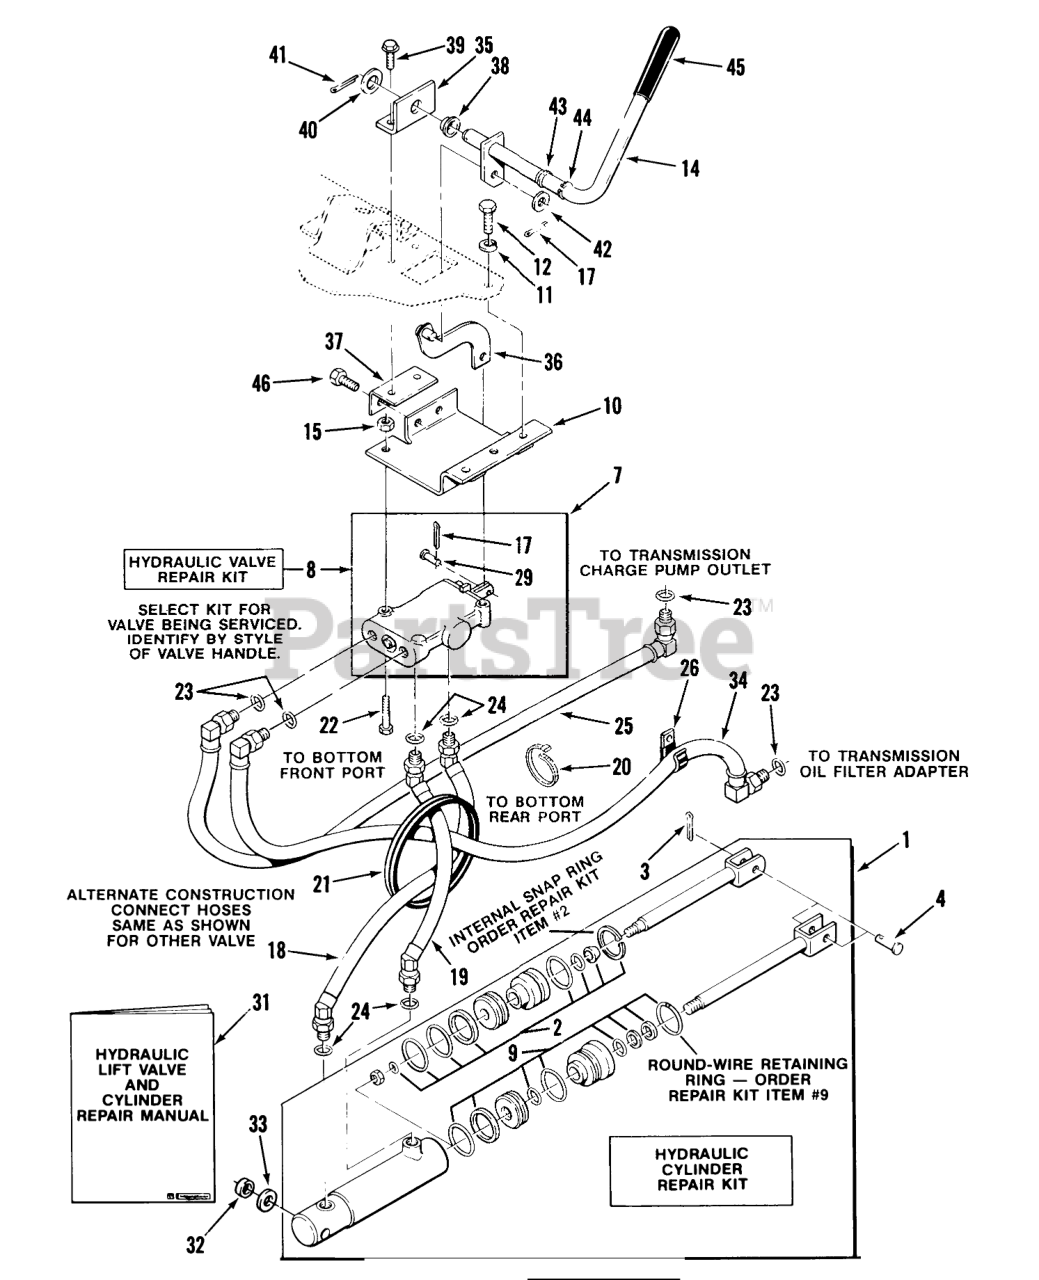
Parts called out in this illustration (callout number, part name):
1	CYLINDER
1	Hydraulic Cylinder 520-HC
2	S/A O-RING&GASKET AS
4	CLEVIS PIN
7	ASS'Y-VALVE
8	S/A 110068 VALVE
9	S/A 108872 HYD CYL
10	ASS'Y-VALVE SUPPO B
11	Lockwasher
12	Bolt
14	ASSY-LEVER LIFT
15	Nut
16	C-HOOK
17	Cotter Pin
18	Hose ASM-Hydraulic
19	Hose ASM-Hydraulic
20	PLASTIC TIE
21	GROMMET
22	Bolt 1/4-20 x 2
23	0-Ring
24	O RING
25	ASSY HOSE HYDRAULIC
26	CLIP
29	Pin
31	Repair Manual
32	Spacer
32	SPACER
33	WASHER
34	ASSY HYD HOSE
35	SUPPORT-LEVER ASS B
36	ASS'Y-BAR LIFT B
37	BRACKET-SUPPORT B
38	NYLINER BUSHING
39	Bolt
40	SHIM-WASHER
41	Pop Rivet
43	BUSHING-NYLINER
44	Grip Ring
45	GRIP
46	Bolt
